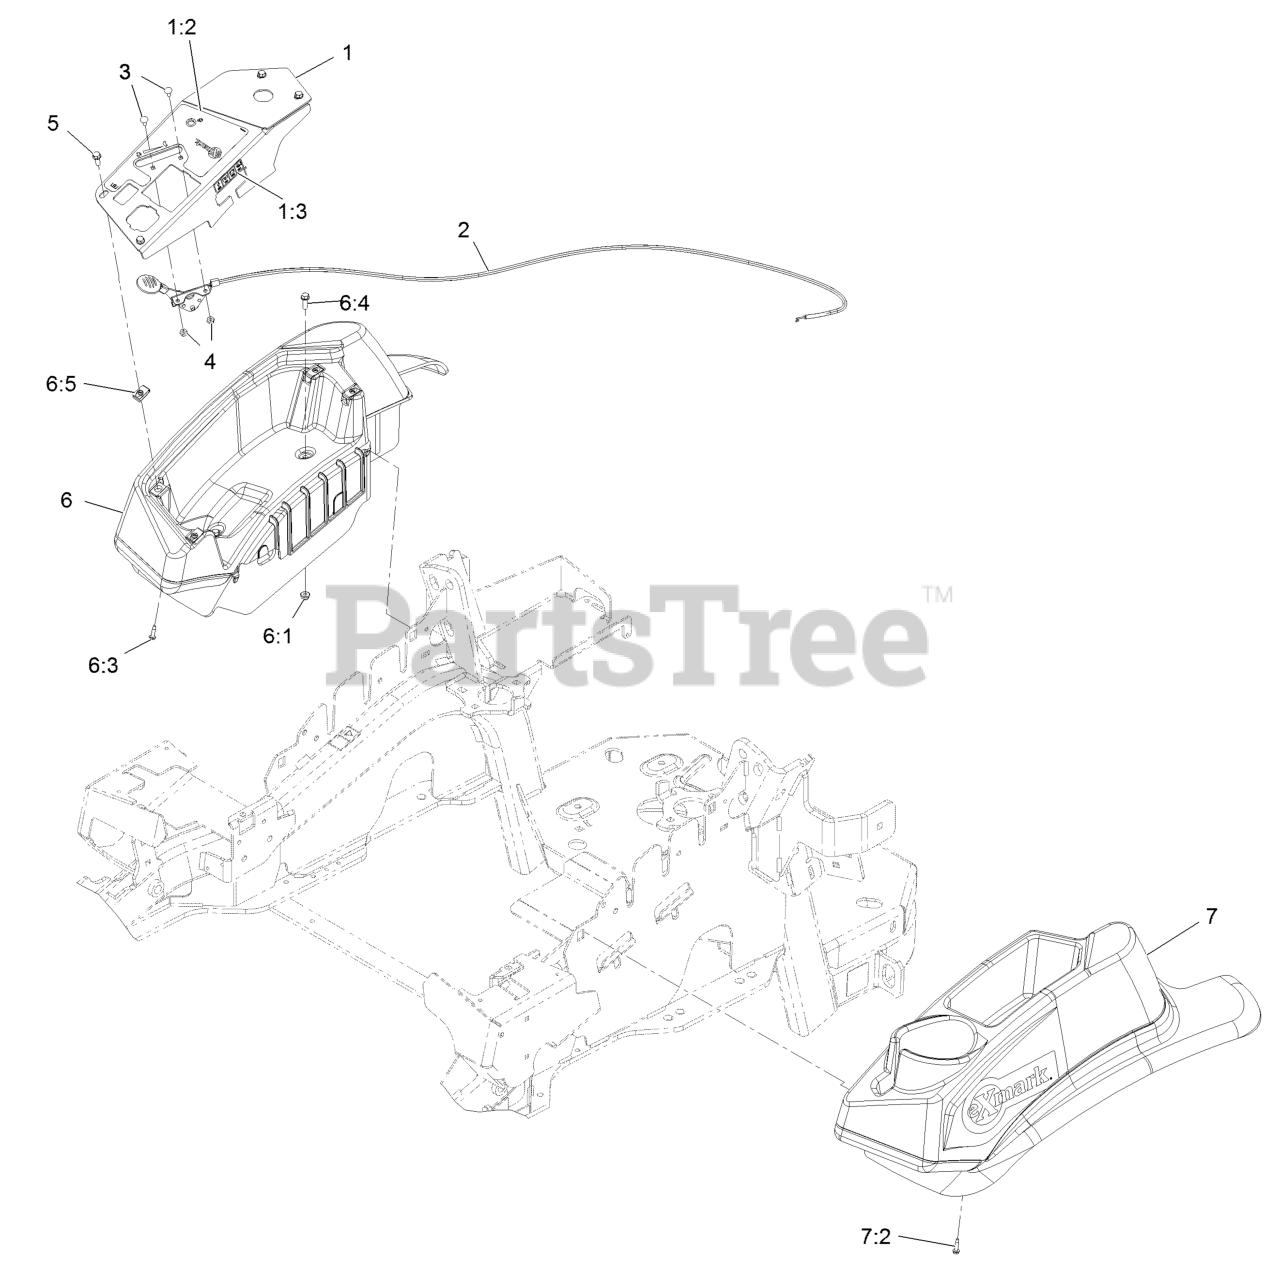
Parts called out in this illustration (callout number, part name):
1	ASM,CONTROL PANEL W/DECAL
1:2	DECAL-CONTROL PANEL EFI
1:3	DECAL-FUSES
2	ASM,THROTTLE CABLE
3	BOLT-CARR
4	NUT-LOCK, NI
5	SCREW-HWH
6	CONSOLE,RH NARROW ASM
6:3	SCREW,THD FORM,HWH
6:4	SCREW-HWH
6:5	Nut-Retainer-Panel 1/4-20
7	CONSOLE.LH NARROW ASM
7:2	SCREW,THD FORM,HWH
